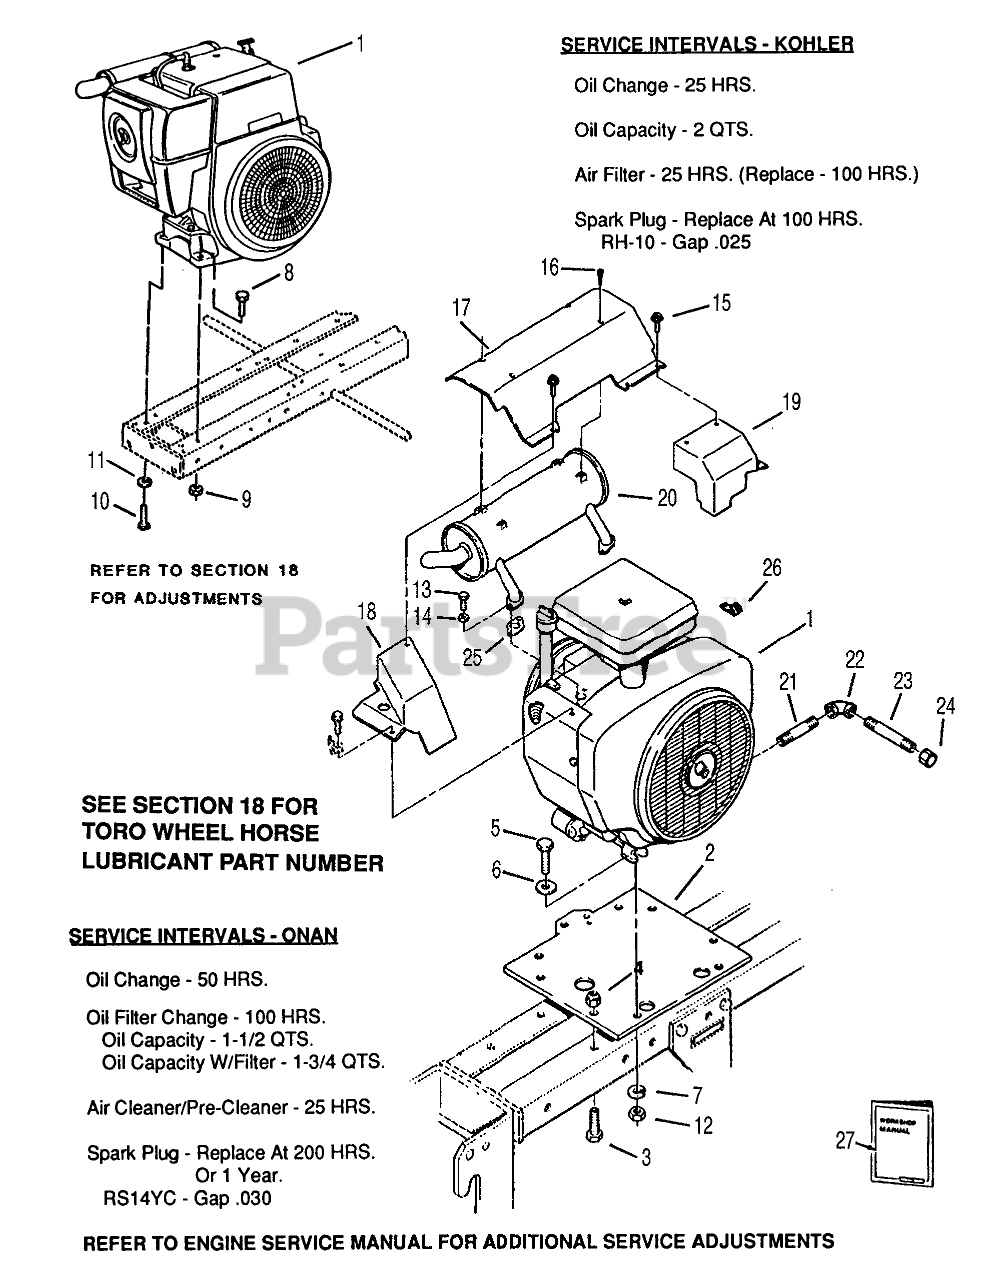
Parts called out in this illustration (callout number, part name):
2	PLATE-ENGINE B
3	Bolt
4	E.S. Nut 3/8-16
5	Bolt
6	Washer
7	LOCKWASHER
8	BOLT
9	NUT
10	BOLT
11	LOCKWASHER
12	Nut
13	Bolt
14	Lockwasher
15	Bolt
16	Screw
17	Air Deflector
18	LH Exhaust Cover
19	RH Exhaust Cover
20	MUFFLER-EXHAUST
21	Pipe
22	ELBOW 3/8 90 DEG
23	PIPE-NIPPLE 3/8 X 4"
24	Cap
25	Exhaust Gasket
26	J-CLIP
27	Magnum Kohler Service & Repair Manual
